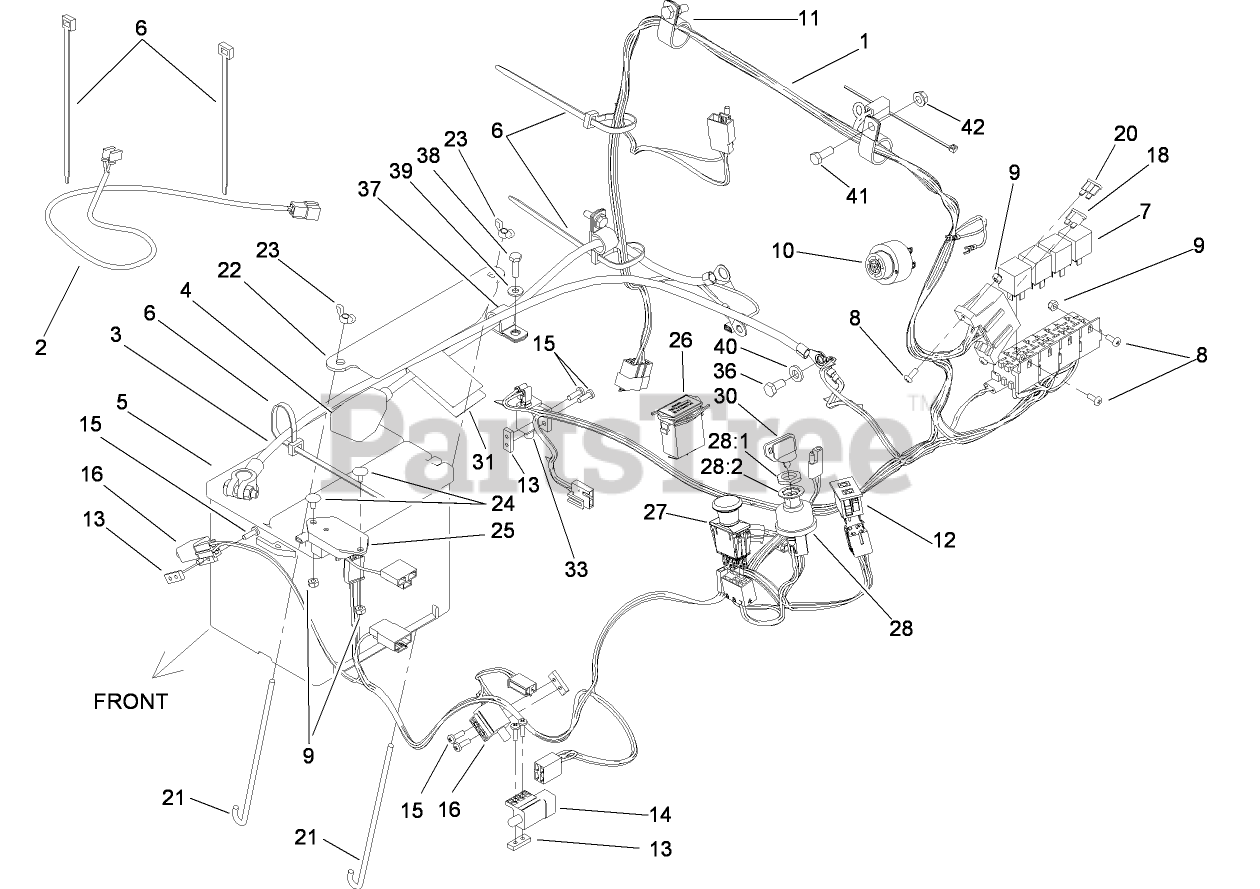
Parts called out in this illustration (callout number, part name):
1	HARNESS-WIRE
2	HARNESS-WIRING, SEAT
3	CABLE-BATTERY, NEGATIVE
4	CABLE-BATTERY, POSITIVE
5	BATTERY-DRY
6	TIE-PLASTIC
9	NUT-LOCK, NI
10	ALARM-TONE, DUAL
11	R-CLAMP
12	LAMP-WARNING
13	PLATE-TAPPED
14	SWITCH
15	SCREW-PPH
16	SWITCH-OPEN, NORMALLY
18	FUSE-BLADE, 10 AMP
20	FUSE-BLADE, 30 AMP
21	Bolt-Holddown
22	HOLDDOWN-BATTERY
23	WINGNUT
24	BOLT-CARR
25	MODULE-DELAY, SEAT
26	METER-HOUR
27	SWITCH-PTO
28	SWITCH ASM
28:1	NUT-HH
28:2	WASHER-TOOTH, INTERNAL
30	KEY-IGNITION
31	DECAL-INSTRUCTIONS, CHARGING
33	SWITCH-CLOSED, NORMALLY
36	SCREW-HH
37	CLIP-LOOM
38	SCREW-HH
39	WASHER-FLAT
40	WASHER-PLAIN
41	SCREW-HH
42	NUT-HF
